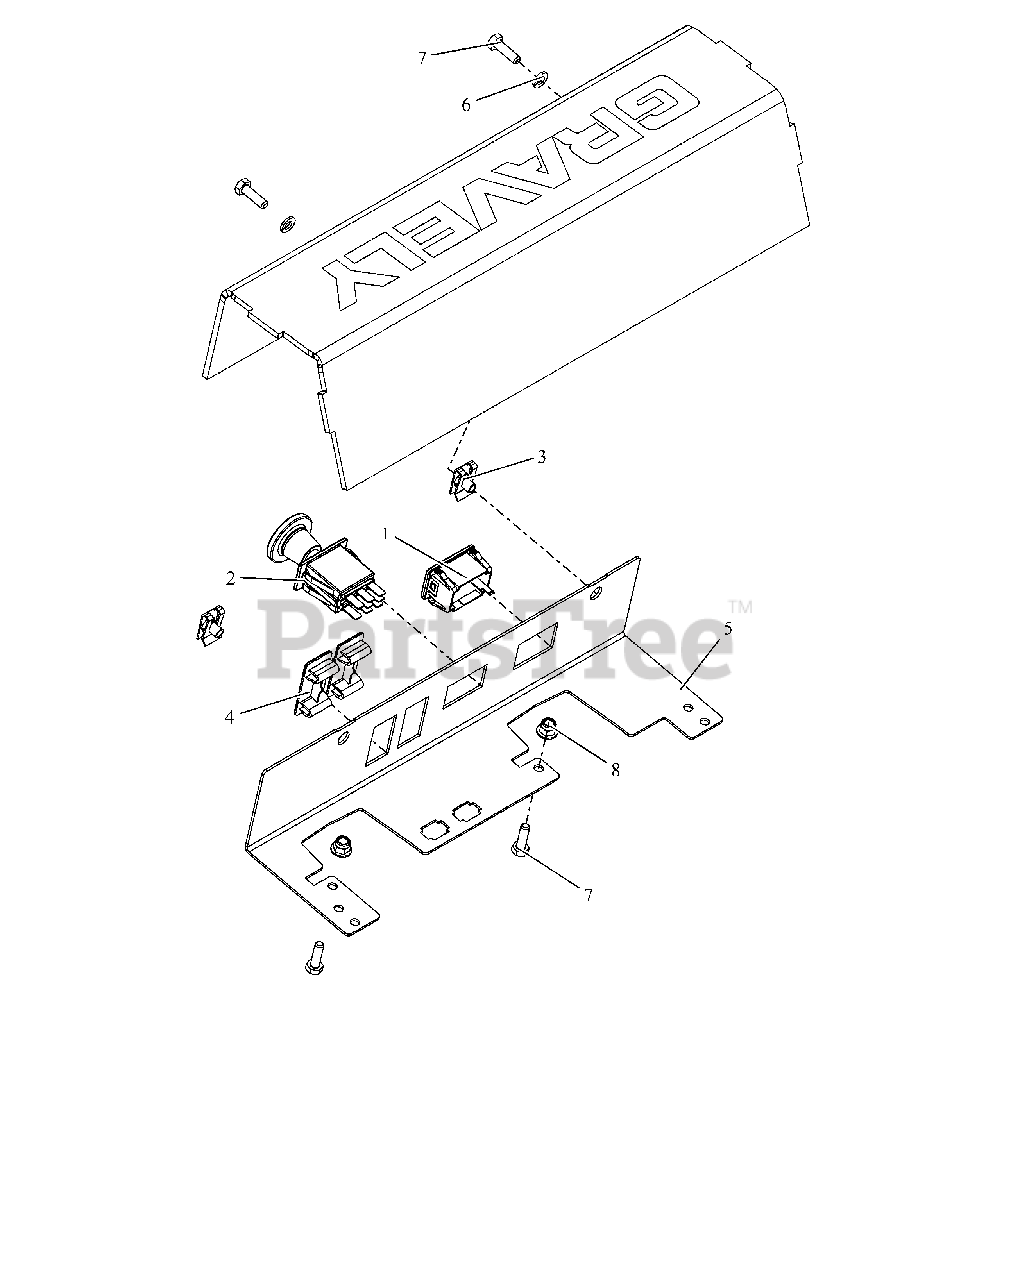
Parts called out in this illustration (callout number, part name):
1	METER, HOUR SMART SENSE W/O SV
2	SWITCH, CLUTCH (WITH GRAPHIC)
3	NUT-RTNR M6X1
4	PLUG,DASH PANEL
5	BRKT, ELEC
6	WSHR,LK-REG .250X.062 ZCC
7	BLT, HEX M6-1.0 X 20 G8.8 ZCC
8	NUT,NYL-FLG M6-1.0 G8.8 ZCC
